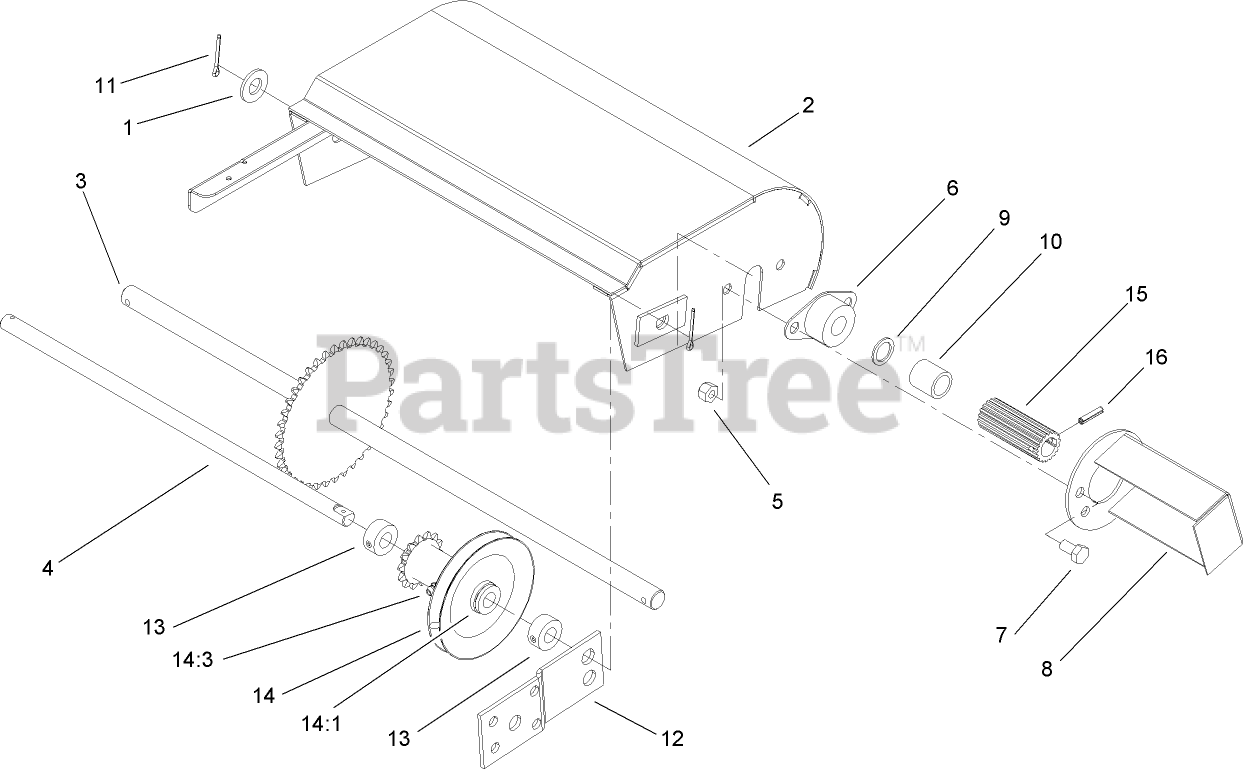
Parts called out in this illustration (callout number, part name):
1	WASHER-FLAT
3	SHAFT-WHEEL, FRICTION
4	SHAFT-IDLER
5	NUT-LOCK, NI
6	BEARING-FLANGE
7	SCREW-HH
9	WASHER
10	SPACER
11	PIN-COTTER
12	BRACKET-MOUNTING
13	COLLAR
14	IDLER ASM
14:1	BUSHING-FLANGE
14:3	FITTING-GREASE
15	WHEEL-FRICTION
16	PIN-ROLL, SLOTTED
